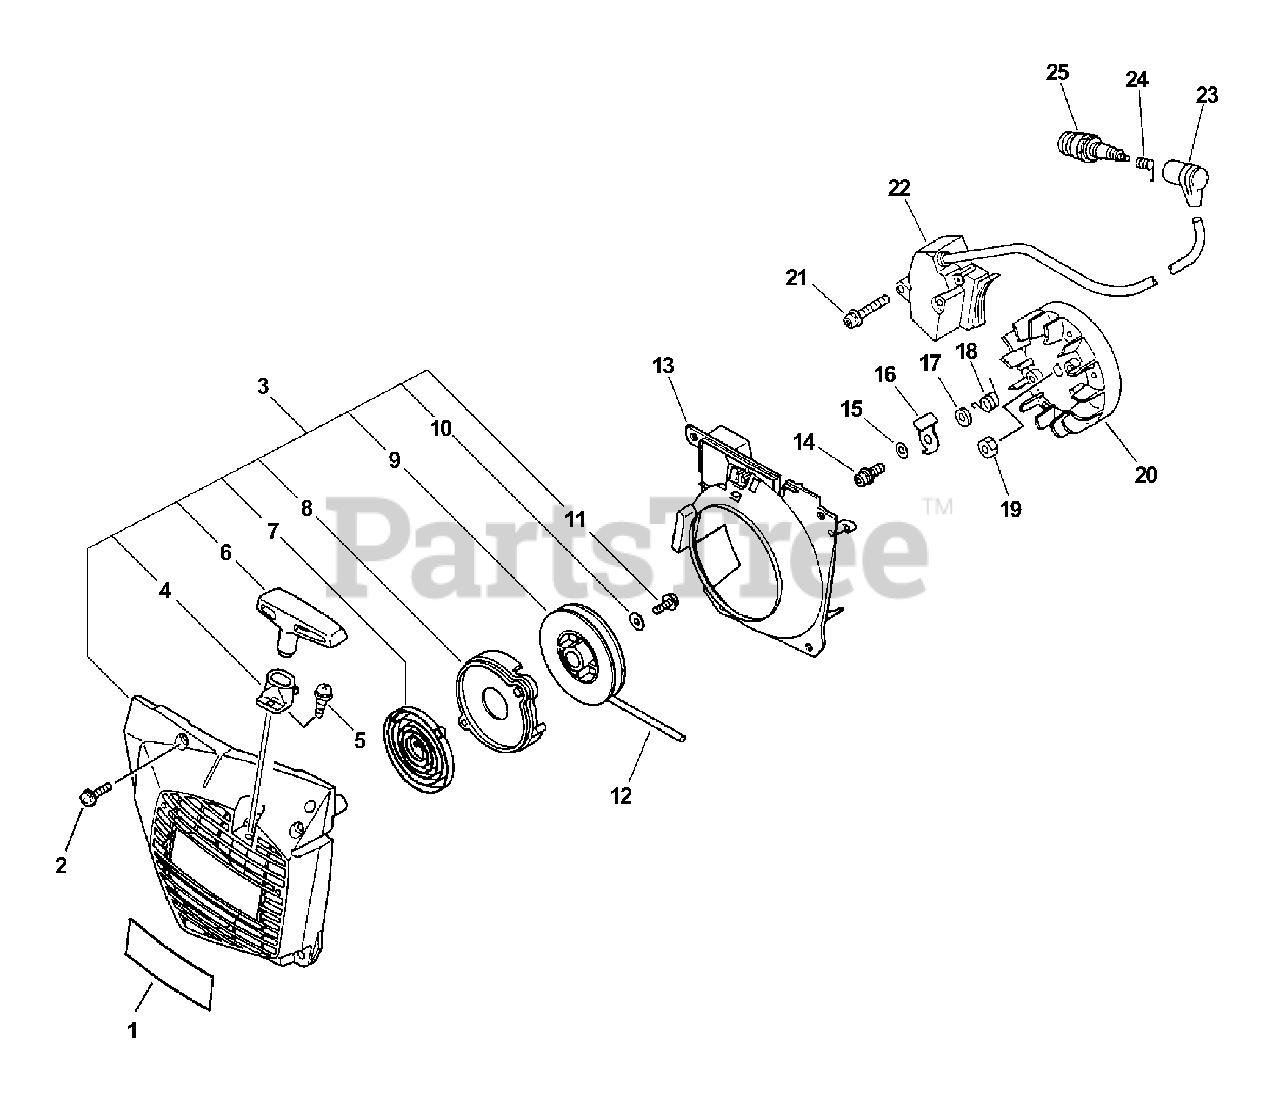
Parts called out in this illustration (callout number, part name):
2	SCREW 5×18
3	STARTER ASSY
4	GUIDE, ROPE
5	SCREW 3×14
6	GRIP, STARTER
7	SPRING, RECOIL
8	PLATE, STARTER
9	REEL, ROPE
10	WASHER 5.2×16×1.0
11	SCREW 5×12
12	ROPE, STARTER
13	COVER, FAN
14	BOLT 5×14
15	WASHER 5.5×12×0.8
16	PAWL, STARTER
17	SPACER 5.2×8×2.1
18	SPRING, TORSION
19	NUT, FLANGE M8
20	FLYWHEEL
21	BOLT 4×30
22	COIL, IGNITION
23	CAP, SPARK PLUG
24	TERMINAL, SPARK PLUG
25	SPARK PLUG - BPM7A
25	SPARK PLUG - RCJ6Y
